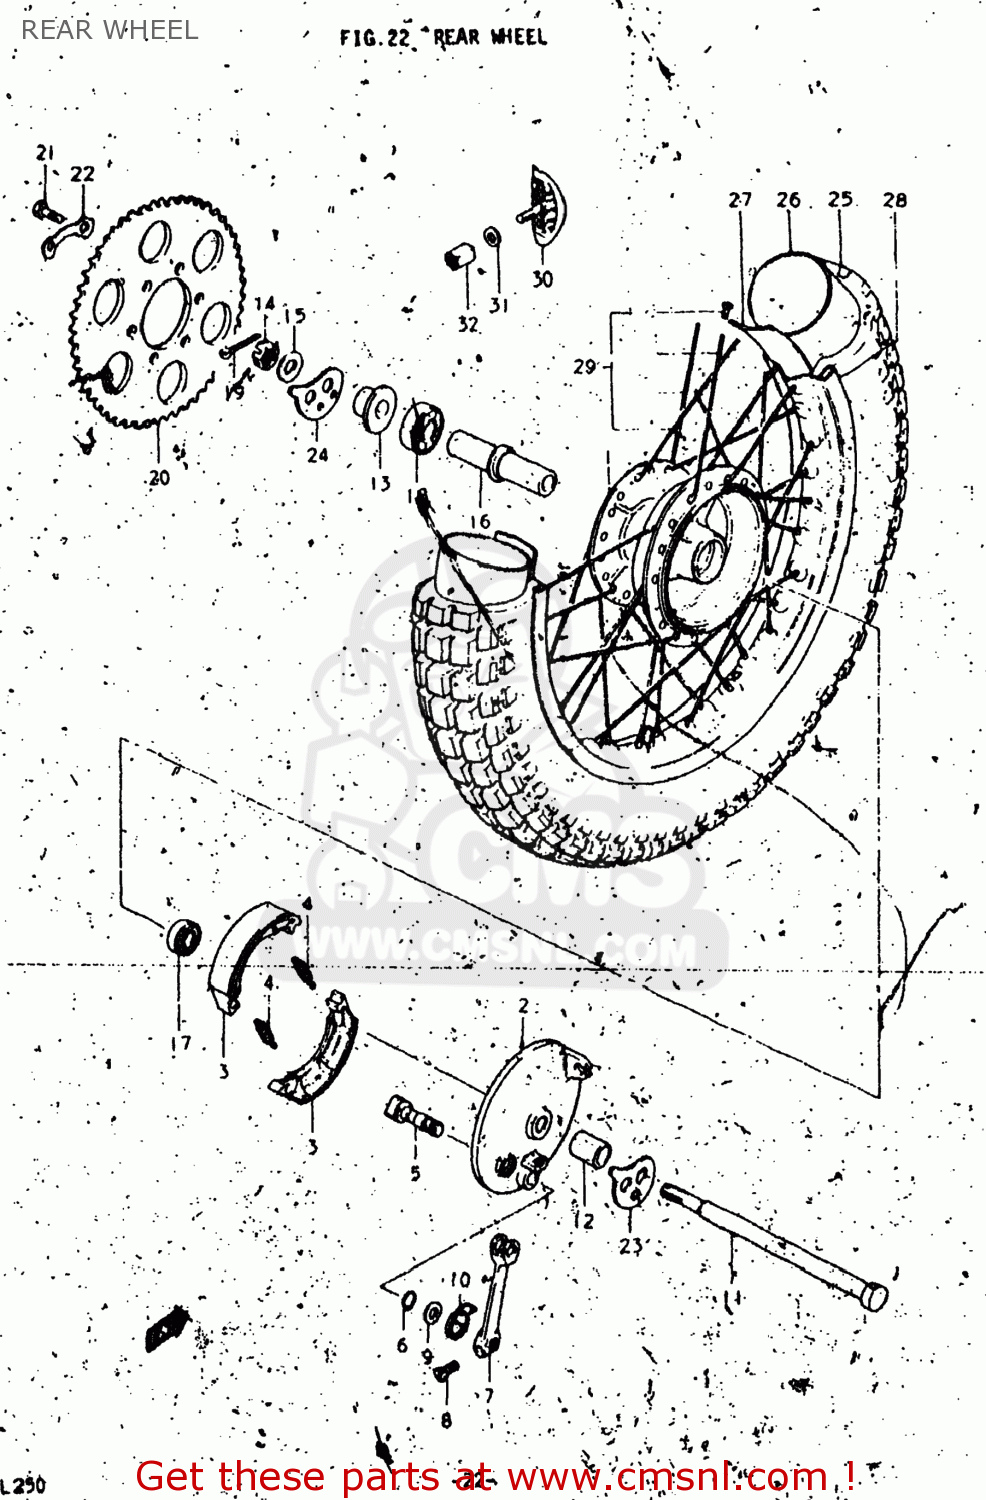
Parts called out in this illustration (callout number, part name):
0	WHEEL SET,REAR
1	HUB,REAR WHEEL
2	PANEL,REAR HUB
3	SHOE,BRAKE
4	SPRING(L:34)
5	CAM,FR BRAKE
6	O RING(D:2.5,ID:11.4)
7	LEVER,REAR BRAKE CAM
8	BOLT
9	WASHER(12.5X20X1)
10	SPRING
11	AXLE,REAR
12	SPACER
13	SPACER,REAR AXLE
14	NUT (12MM)
15	WASHER
16	SPACER,REAR HUB BEARING
17	BEARING
18	BEARING
19	COTTER PIN
20	SPROCKET,REAR
21	BOLT(8X30)
22	WASHER
23	ADJUSTER,CHAIN
24	PLATE,CHAIN ADJUSTER GEAR
25	TIRE
26	TUBE ASSEMBLY,WHEEL,INNER
27	PROTECTOR,WHEEL,INNER
28	RIM,REAR WHEEL
29	SPOKE SET,REAR
30	STOPPER,BEAD
31	WASHER
32	NUT
